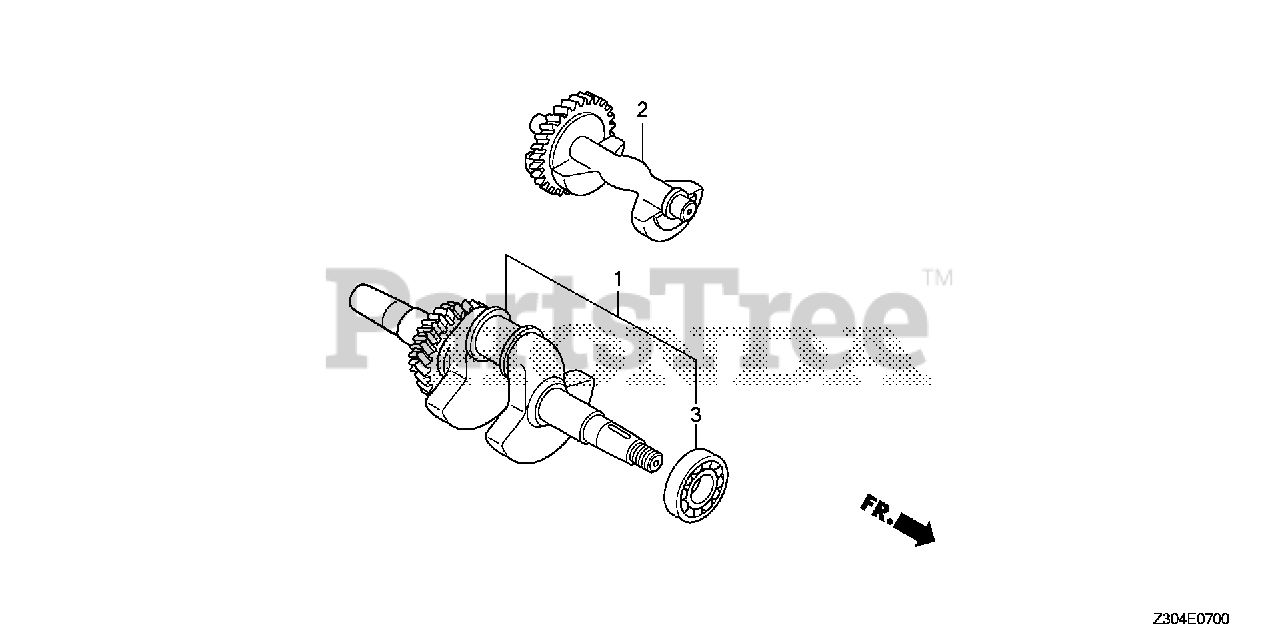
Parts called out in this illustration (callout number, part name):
1	CRANKSHAFT
2	WEIGHT, BALANCER
3	BEARING, RADIAL BALL (6207SH)
